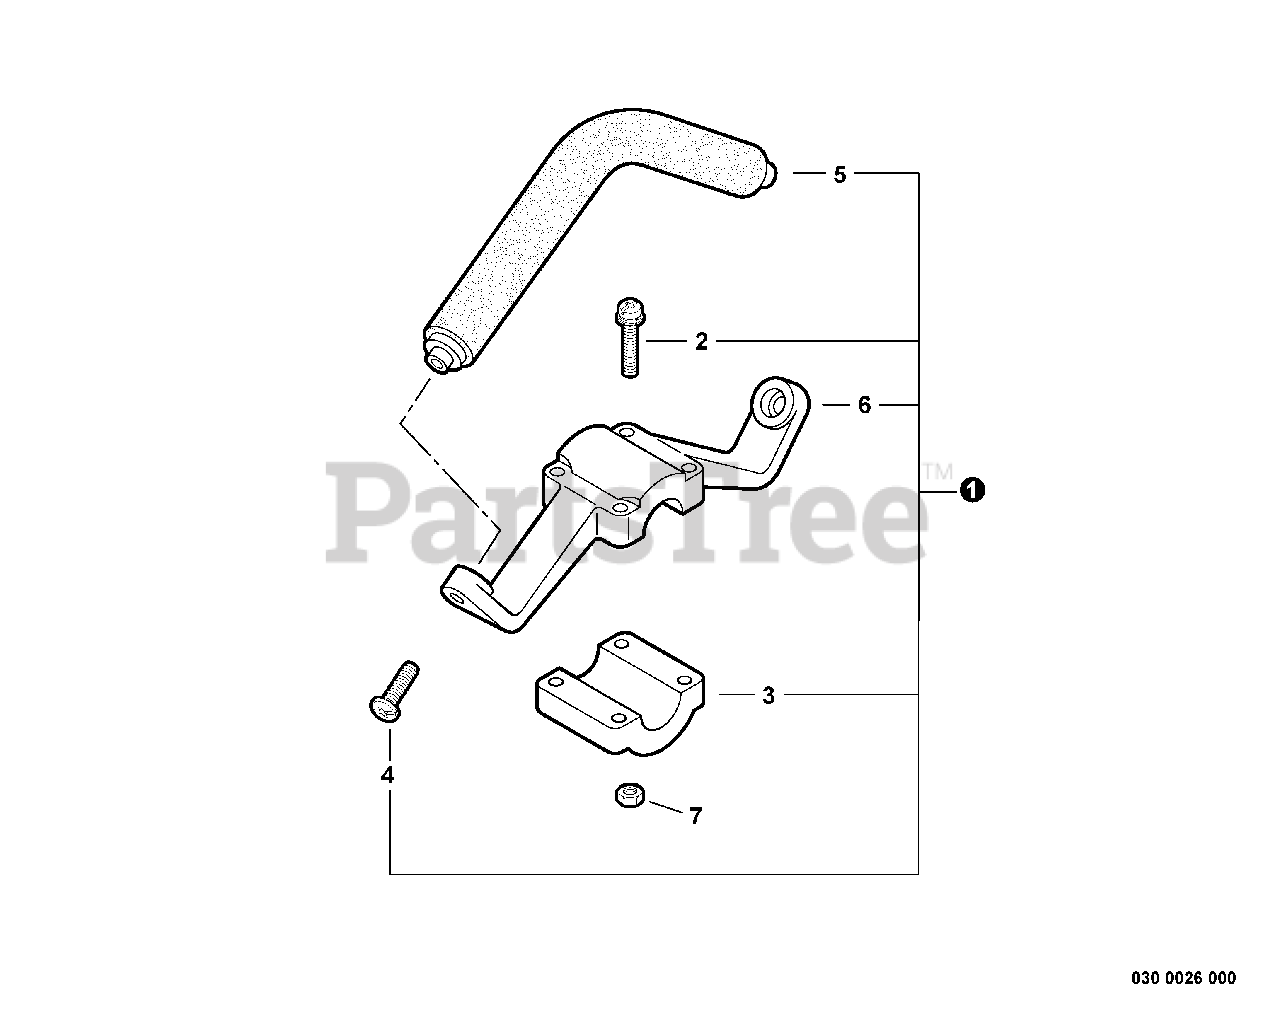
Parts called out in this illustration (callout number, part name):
1	HANDLE ASSY - FRONT
2	SCREW - 5X35
3	BRACKET, HANDLE - LOWER
4	SCREW - 5X14
6	BRACKET, HANDLE - UPPER
